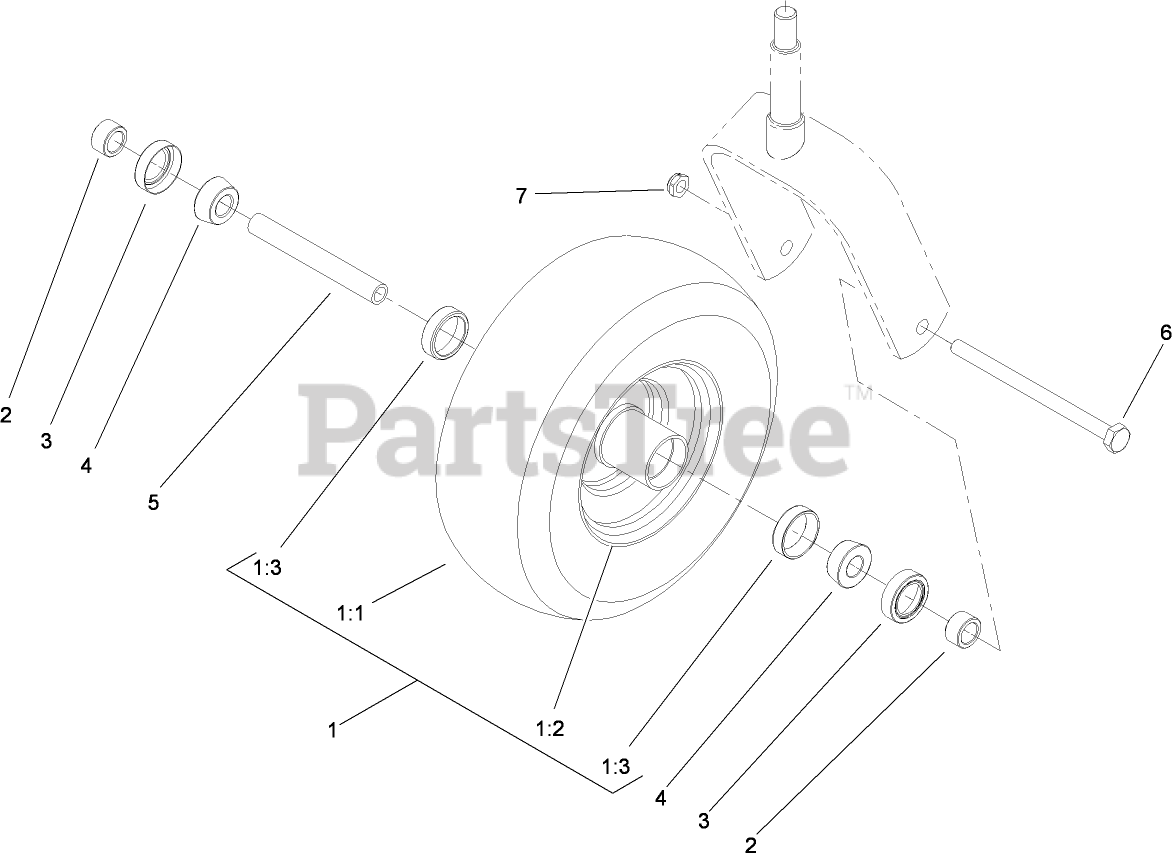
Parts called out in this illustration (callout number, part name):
1	WHEEL and TIRE ASM
1:3	BEARING-CUP
2	SPACER-BEARING
3	SEAL-BEARING
4	BEARING-CONE, TAPER
5	SPACER-CASTER, FRONT
6	SCREW-HH
7	NUT-LOCK, NI
